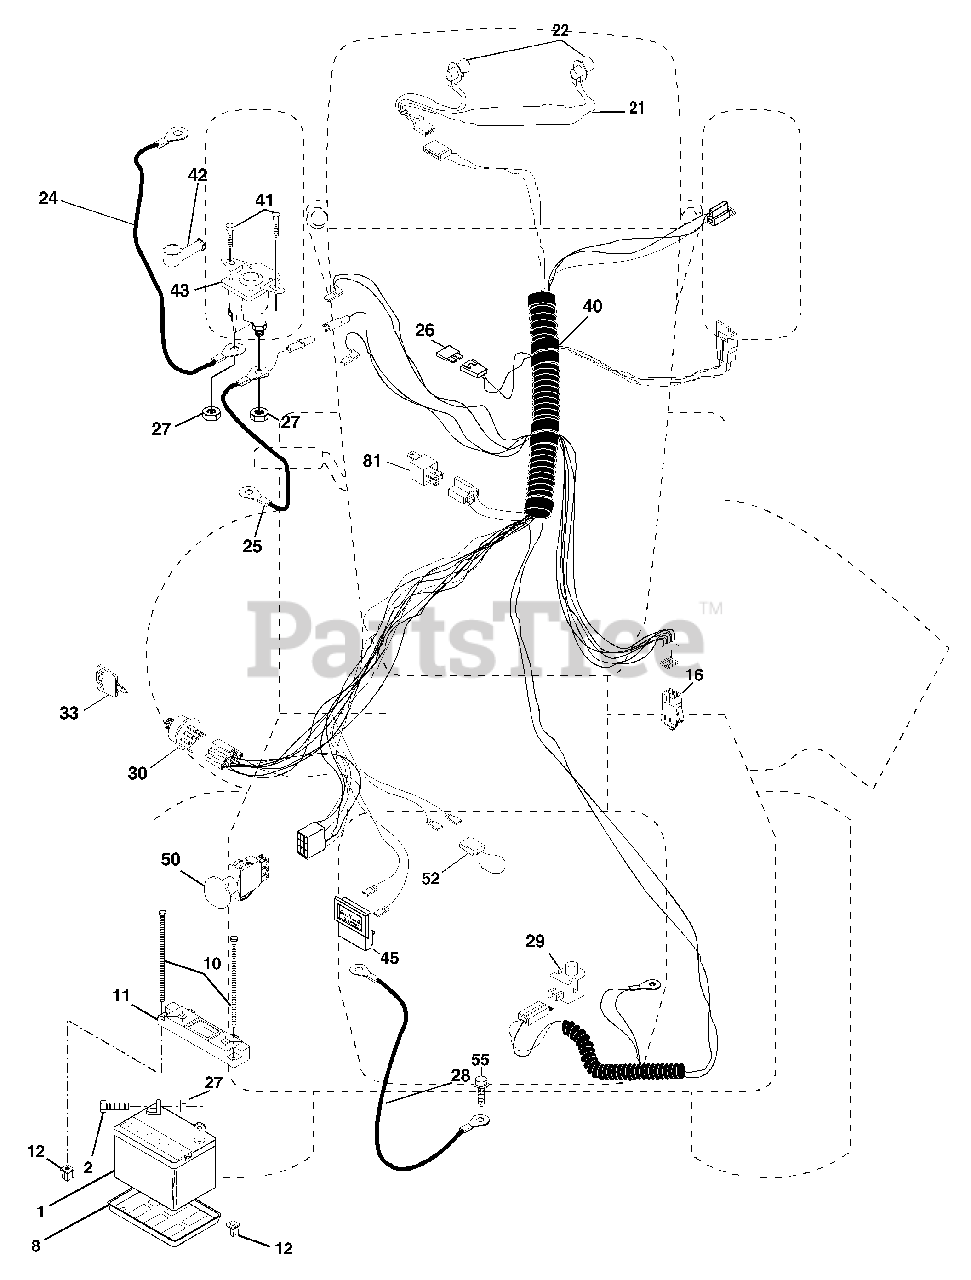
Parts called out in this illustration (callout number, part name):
1	Battery
2	Bolt Hex Hd 1/4-20 UNC X 3/4
8	Tray, Battery
10	Bolt, BTR FRT 1/4-20 x 7.5
11	Hold Down Battery, Front
12	Nut, Push, Nylon
16	Switch Interlock Push-In
21	Harness Asm Light W/4152j
22	Bulb Light
24	Cable Battery
25	Cable Batterywire
26	Fuse
27	Nut Keps Hex 1/4-20 Unc
28	Cable Ground
29	Switch Plunger Normal OP Olive
30	Switch Ign 4 pos w/lights
33	Key Ign
40	Harness Ign.
41	Bolt Blk Fin Hex 1/4-20 x 1/2
42	Cover Terminal Red
43	Solenoid
45	Ammeter Rectangular
50	Switch, PTO
52	Protection wire Loop (Hour Meter)
55	Screw Thdrol 5/16-18 x 1/2
81	Relay Asm
